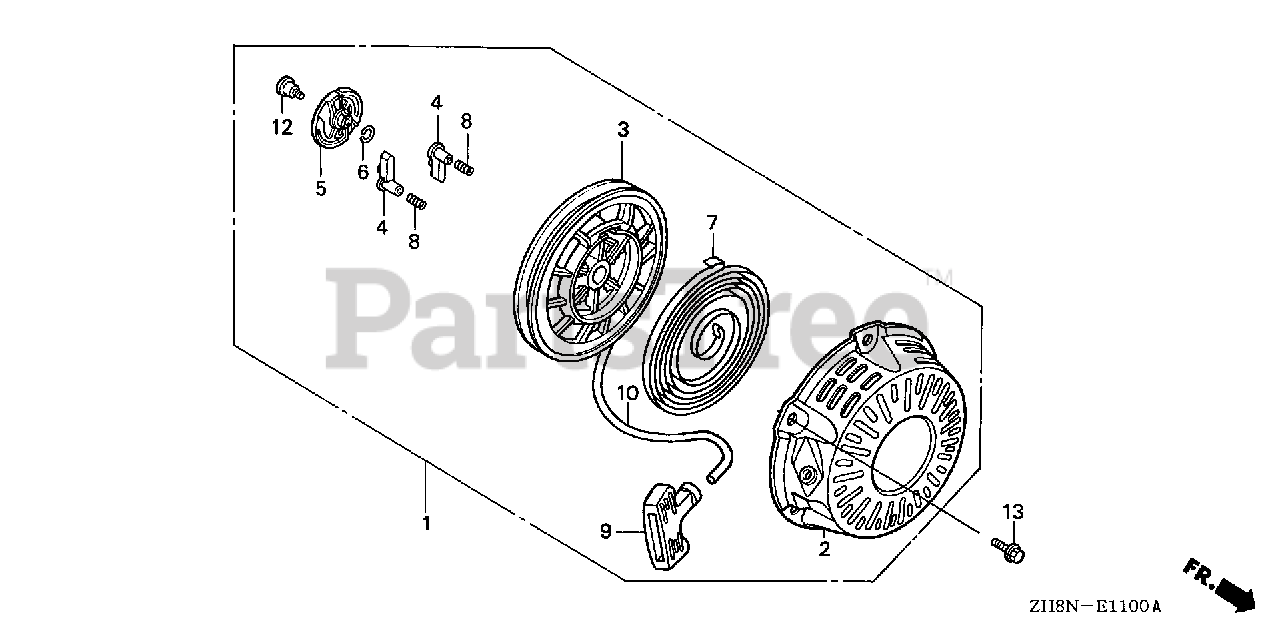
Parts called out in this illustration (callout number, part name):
1	STARTER ASSY., RECOIL *R8* (BRIGHT RED)
2	CASE, RECOIL STARTER *R8* (BRIGHT RED)
3	REEL, RECOIL STARTER
4	RATCHET, STARTER
5	GUIDE, RATCHET
6	SPRING, FRICTION
7	SPRING, RECOIL STARTER
8	SPRING, RETURN
9	KNOB, RECOIL STARTER
10	ROPE, RECOIL STARTER (NA USE ALT:08550-ZG921-11)
12	SCREW, SETTING
13	BOLT, FLANGE (6X10)
